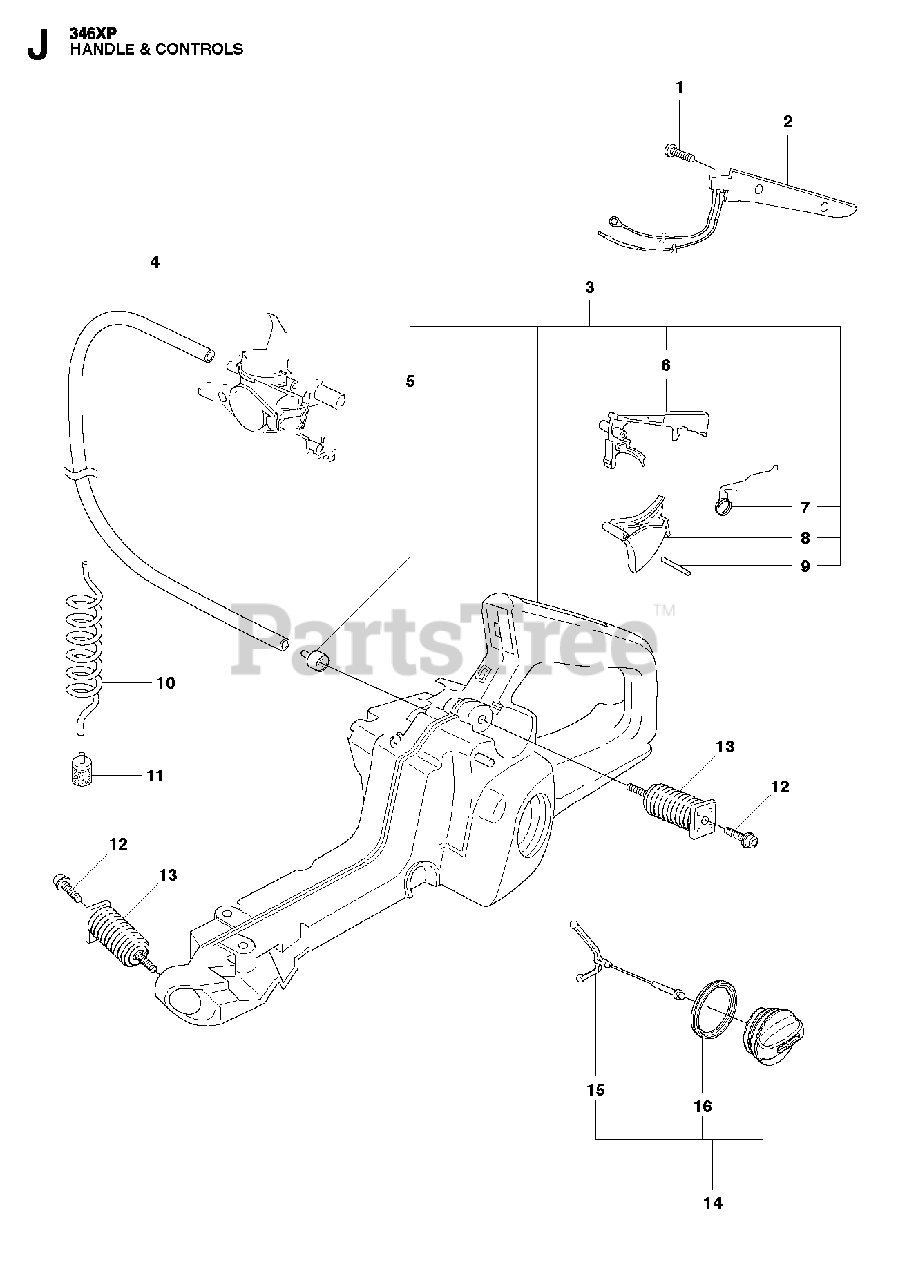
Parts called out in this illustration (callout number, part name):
1	SCREW
2	HANDLE CIRCUIT
4	FUEL HOSE
5	FUEL TANK VENT
6	THROTTLE LOCK
7	SPRING
8	TRIGGER
9	PIN
10	FUEL HOSE
11	FUEL FILTER
13	VIBRATION ABSORBER
14	TANK CAP
15	TANK LOCK
16	SEALING
